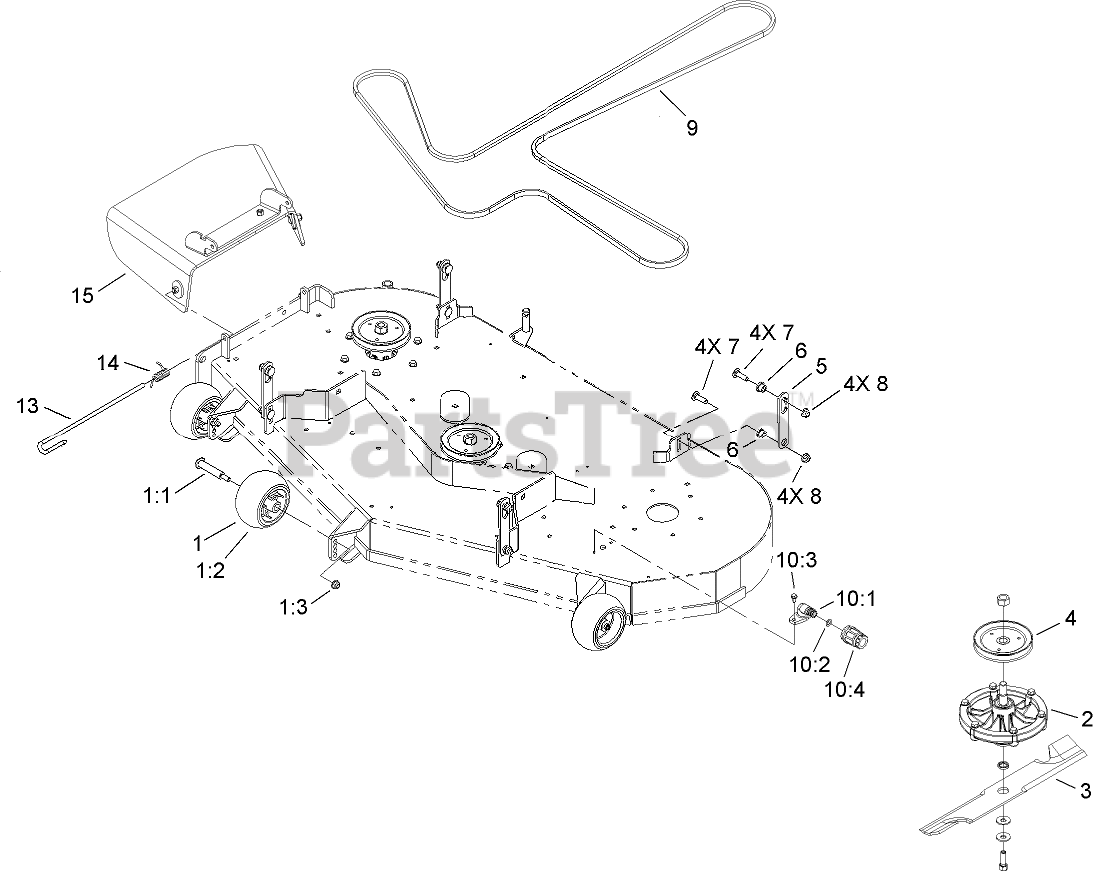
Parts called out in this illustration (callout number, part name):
1	ANTI-SCALP ROLLER KIT
1:1	BOLT-SHOULDER
1:2	ROLLER-SCALP, ANTI
1:3	NUT-HF, NI
2	COMPLETE CUTTER HOUSING ASM
3	BLADE-NOTCHED
4	PULLEY-DECK
5	HANGER-DECK
6	SPACER-STRUT
7	BOLT-CARR
8	NUT-HF, NI
9	BELT
10:1	FITTING-WASHOUT
10:2	O-RING
10:3	SCREW-HWH
10:4	CONNECTOR-HOSE
13	PIN-CHUTE
14	SPRING
15	RUBBER DEFLECTOR ASM
